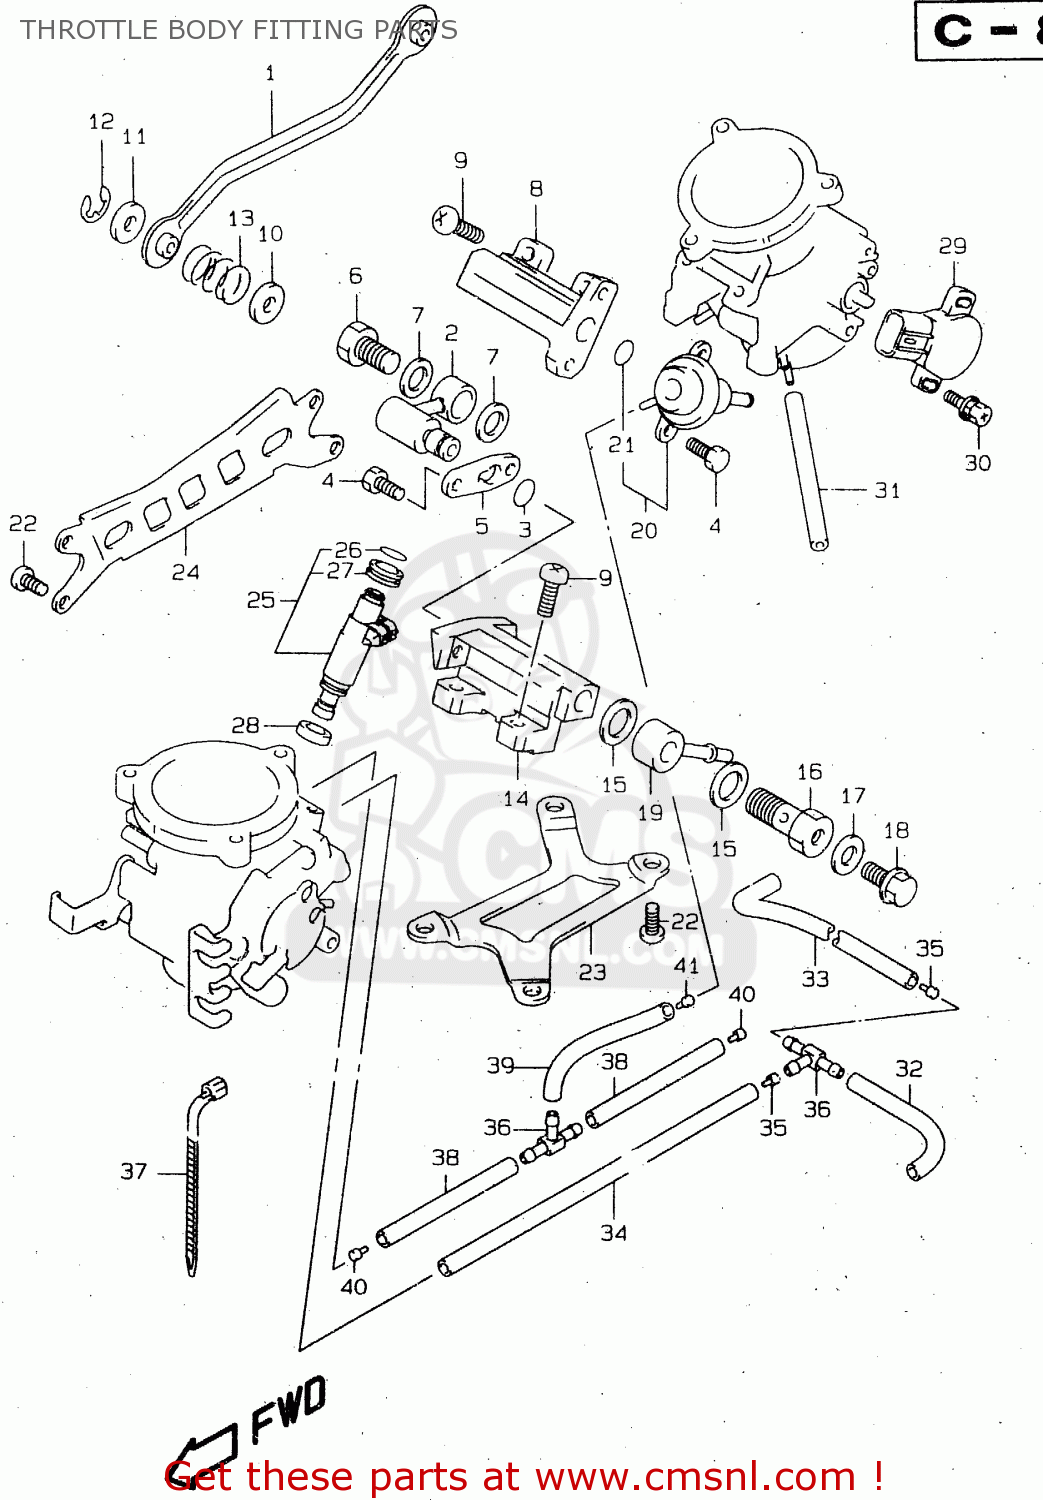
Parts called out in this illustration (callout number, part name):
1	LEVER ASSY
2	PIPE ASSY
3	O-RING
4	BOLT
5	PLATE
6	BOLT
7	WASHER
8	PIPE,DELIVERY
9	SCREW
10	RING
11	RING
12	E RING,ACCELETION LEVER
13	SPRING
14	PIPE,DELIVERY
15	GASKET,UNION BOLT (NAS)
16	BOLT,UNION FUEL FILTER
17	GASKET(5.8X13X1.2) (NAS)
18	UNION BOLT,AIR VENT
19	UNION,FUEL HOSE
20	REGULATOR,FUEL
21	O RING
22	SCREW
23	PLATE
24	PLATE
25	INJECTOR ASSY,FUEL
26	O RING
27	GROMMET
28	CUSHION,FUEL INJECTOR
29	SENSOR ASSY,THROTTLE
30	SCREW
31	HOSE(3.5X7.5X600)
32	HOSE(3X7X600)
33	HOSE
34	HOSE
35	JET,AIR(180)
36	3WAY,VACUUM HOSE
37	CLIP
38	HOSE(3X7X600)
39	HOSE(3X7X600)
40	JET
41	JET
